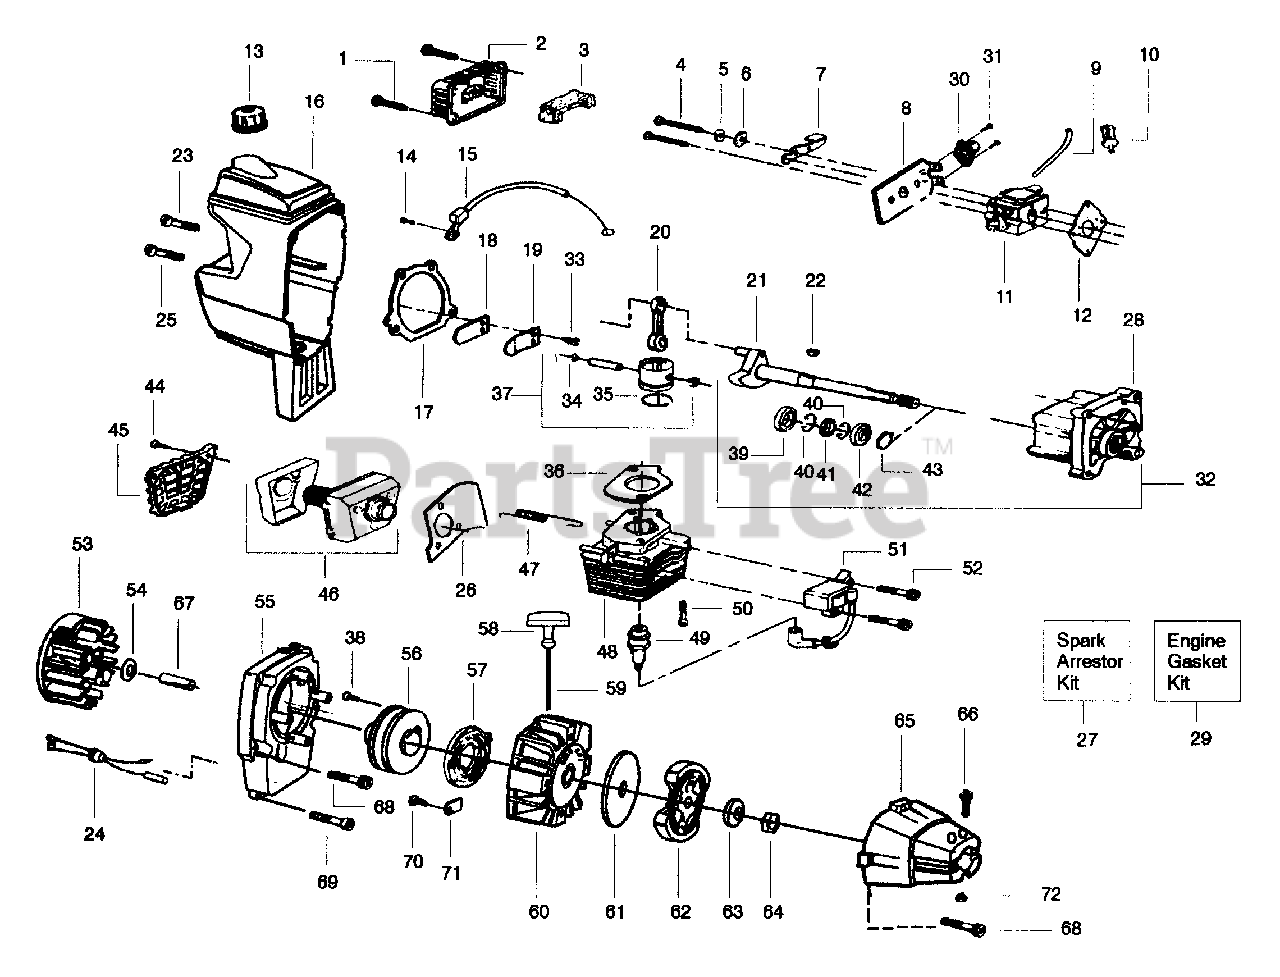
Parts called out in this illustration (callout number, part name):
2	Air Filter Cover
3	Air Filter
5	Choke Spacer
7	Choke Shutter
8	Air Filter Plate
9	Fuel Line Kit
10	Fuel Pick-up Ass'y.
11	Carburetor Ass'y. Kit
12	Gasket-Carburetor
13	Fuel Cap Ass'y.
15	Throttle Cable Ass'y.
16	Shroud/Tank Ass'y.
17	Gasket-C'case/Shroud
18	Reed Valve
19	Reed Stop
20	Connecting Rod Ass'y.
21	Crankshaft Ass'y.
22	Flywheel Key
24	Leadwire/Grommet Ass'y.
26	Heat Shield/Air Dam
27	Spark Arrestor Kit
28	Crankcase Ass'y.
29	Engine Gasket Kit
30	Bulb Ass'y.
32	Crankcase/Crankshaft Ass'y.
34	Piston Pin Retainer
35	Piston Ring
36	Gasket-Cylinder
37	Piston Kit
39	Inner Bearing
40	Retaining Ring
41	Crankshaft Seal
42	Outer Bearing
43	Retaining Ring-C'shaft
45	Muffler Guard
46	Muffler Kit
47	Muffler Spring
48	Cylinder Kit
49	Spark Plug (RCJ-8Y)
51	Ignition Module
53	Flywheel Ass'y.
55	Fan Housing
56	Starter Pulley Kit
57	Starter Spring
58	Starter Handle
59	Rope Kit
60	Pulley Housing Ass'y.
61	Washer-Clutch
62	Clutch Ass'y. Kit
63	Washer-Bevel
65	Clutch Housing
67	Spacer-Clutch
71	Retainer
